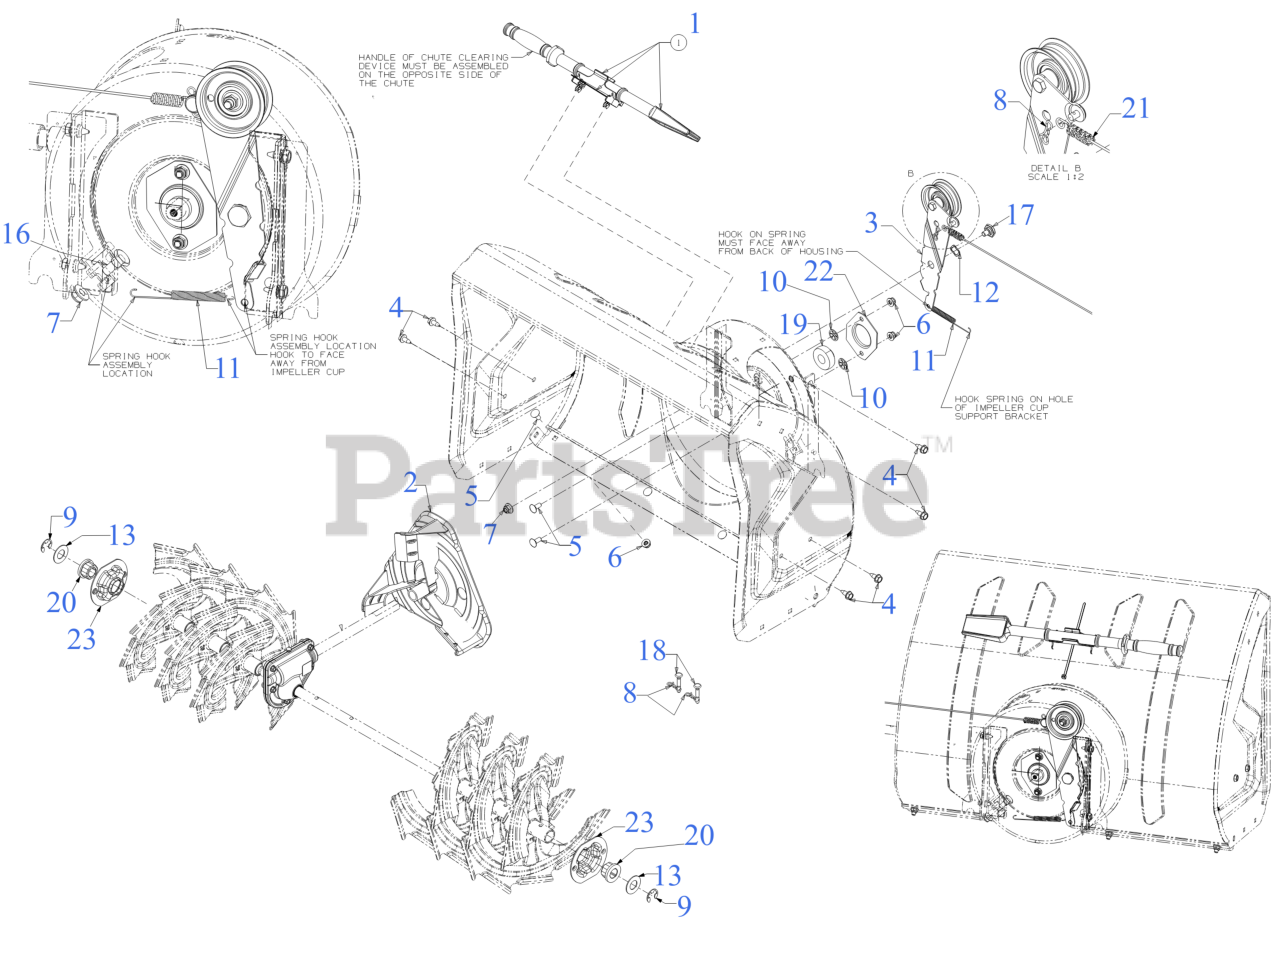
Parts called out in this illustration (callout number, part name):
1	CLEANOUT TOOL
1	CLEANOUT TOOL MOUNTING CLIP
1	7" CABLE TIE
3	IDLER BRACKET
3	FLAT IDLER PULLEY 2.75 OD
3	HEX SCREW 3/8-16 x 1.75 GR5
4	SCREW 5/16-18 x .750
5	CARRIAGE BOLT 5/16-18 x .75
6	FLANGE LOCK NUT 5/16-18
8	BOW TIE COTTER PIN 1/4-5/16
10	PUSH ON NUT
11	EXTENSION SPRING .38 OD x 4.59
12	WAVE WASHER .660 ID X.88 OD x .010
13	FLAT WASHER
16	SHOULDER SCREW .498 DIA x .340
17	SHOULDER SCREW .625
18	SHEAR PIN .25 x 1.50 GR2
18	Cub Cadet SHEAR PINS (2X SNOW)
18	Troy-Bilt SHEAR PIN 6PK (04124A)
18	SHEAR PINS QTY 4
19	BEARING W/OUT COLLAR
20	FLANGE BEARING
21	AUGER CABLE 47.48 LG
22	BEARING HOUSING 1.85 ID
